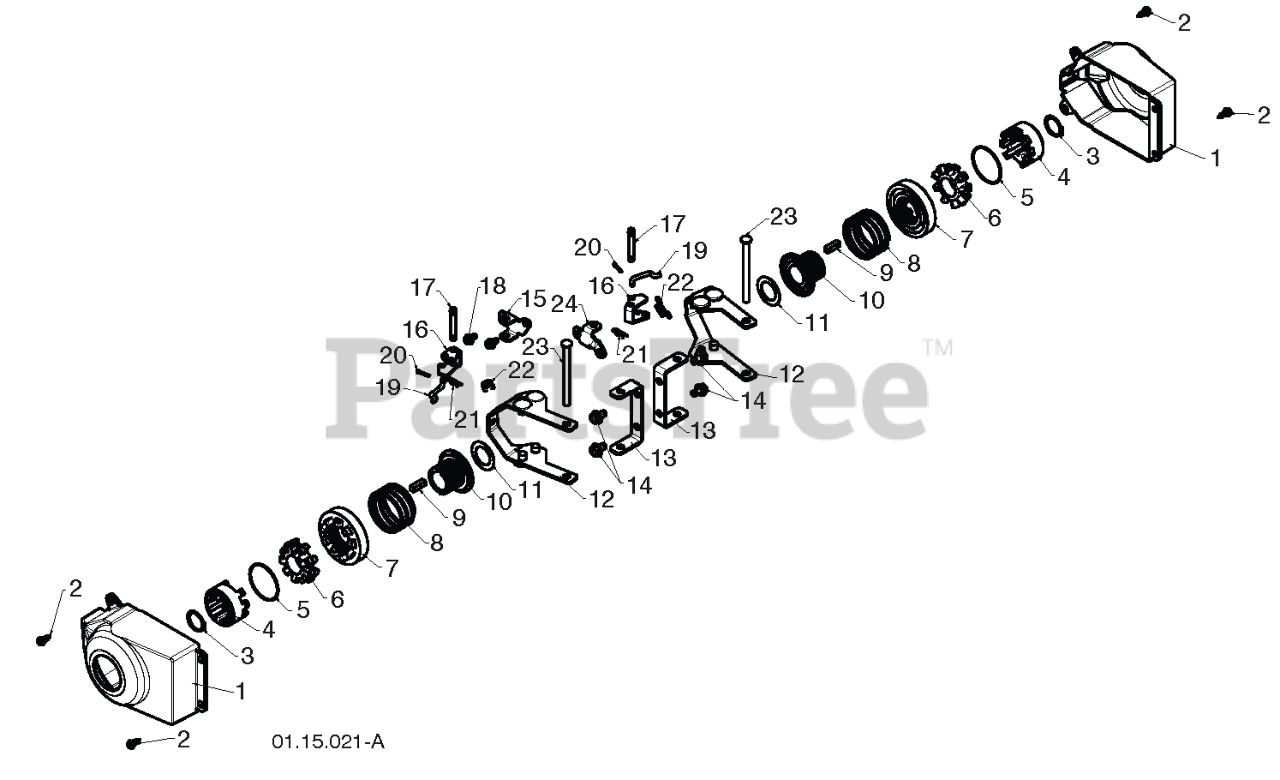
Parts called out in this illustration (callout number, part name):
1	COVER, POWER STEERING
2	SCREW, HEX HEAD, TAPPING
4	DRIVER.WHEEL
5	RING, WIRE RETAINER
6	LOBE WHEEL
7	SLIDE.CLUTCH.SNOW
8	SPRING, CLUTCH SLIDE
9	KEY, SQUARE 1/4 X .875
11	WASHER 1.00
12	YOKE.WELDMENT.STEER.BLACK
13	BRACKET.STEER.PNT.BLACK
14	Screw 5/16-18 x 1/2 Hex, Self Tapping 5/16-18 x 1/2
15	BRKT.STEER.PIVOT.RH
16	BELLCRANK.STEER
17	PIN, STEERING BELLCRANK
18	SCREW 1/4X20
19	LINK.STEER.YOKE
20	RETAINER CLIP
21	RETAINER CLIP PM
22	SPRING LATCH
23	PIN, STEERING LEVER
24	BRACKET.STEER.PIVOT.LH.YZ
